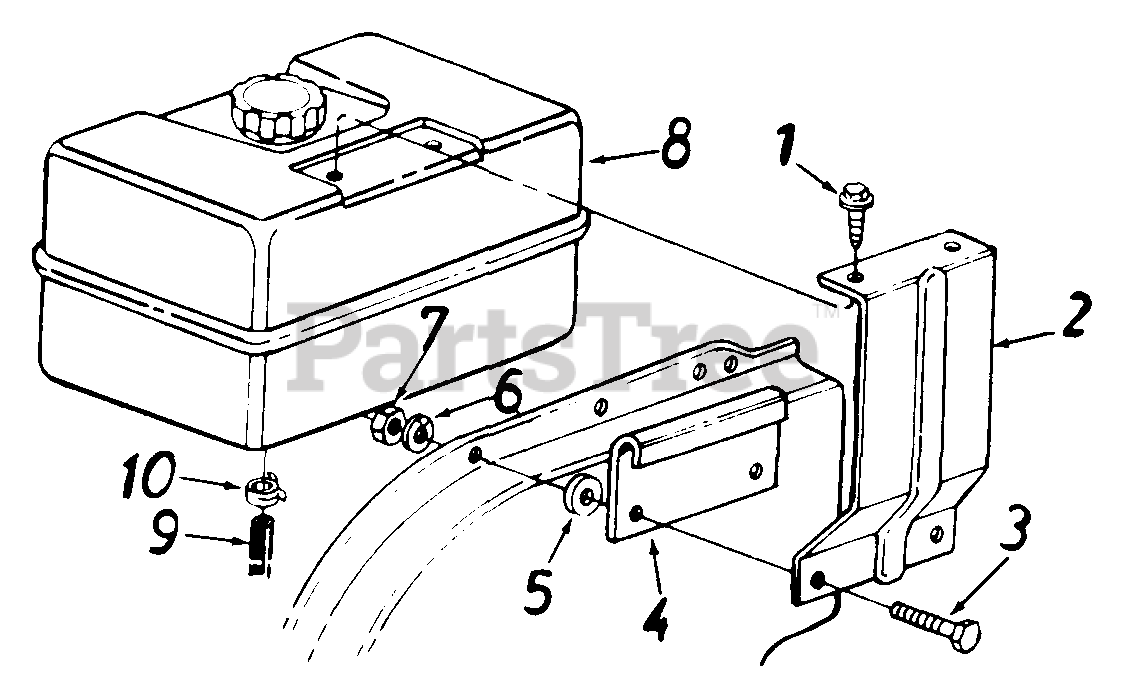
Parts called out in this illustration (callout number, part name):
1	Hex Hd. Hi-Low Scr. 1/4 x .75" Lg.
6	L-Wash. 5/16" I.D.
7	Hex Nut 5/16-18 Thd. (Gr. 5)
8	Fuel Tank Ass'y.
9	Fuel Line - 15" Lg.
10	Hose Clamp 1/2" O.D.
